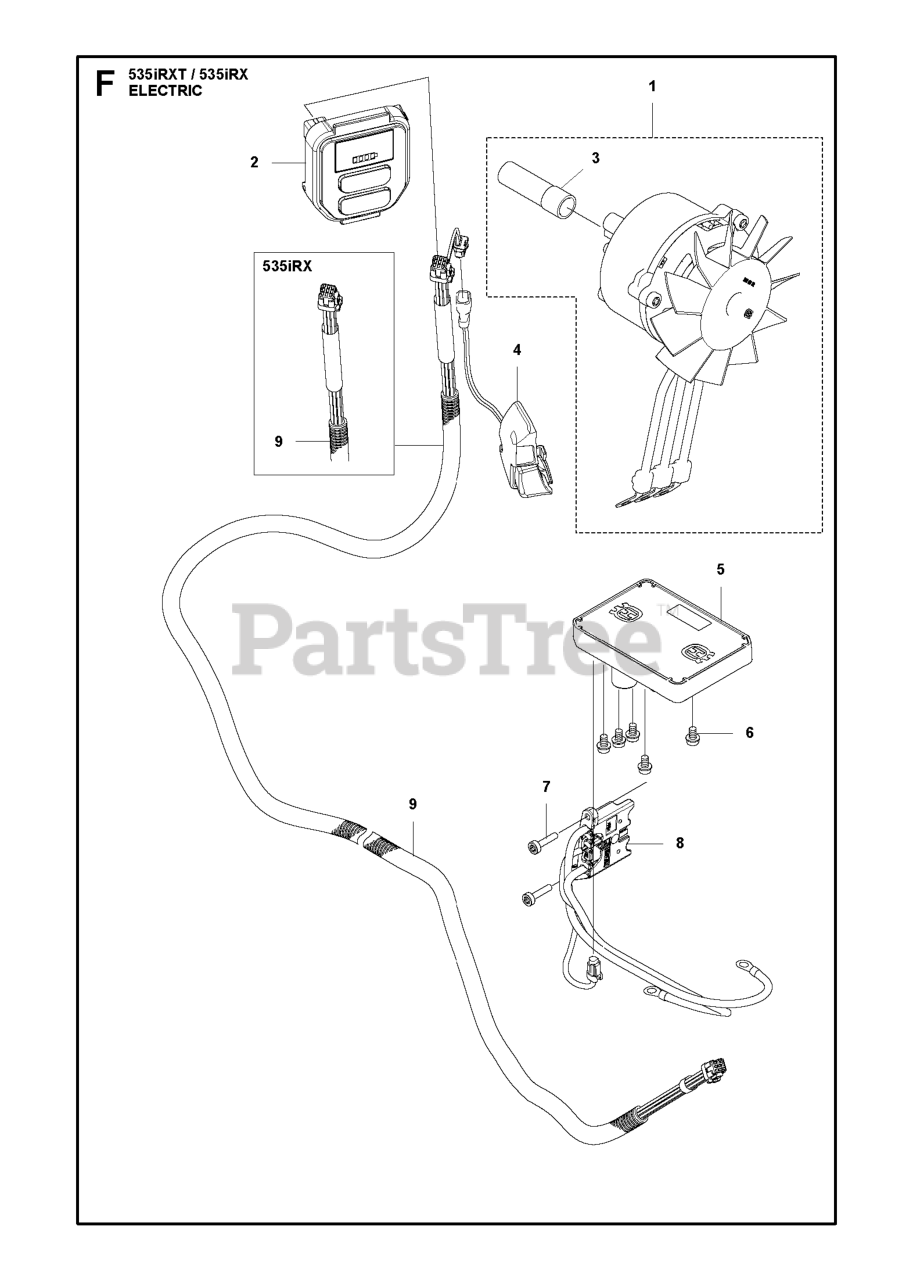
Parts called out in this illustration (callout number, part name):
2	CONTROL PANELS
2	Controls
4	BUTTONS
5	CONTROL UNITS
6	SCREW ITXSCFM M5X8 T27 10.9 Z
7	SCREW ITXSCT PW4.2X18 10.9 ZN
9	HARNESSES
